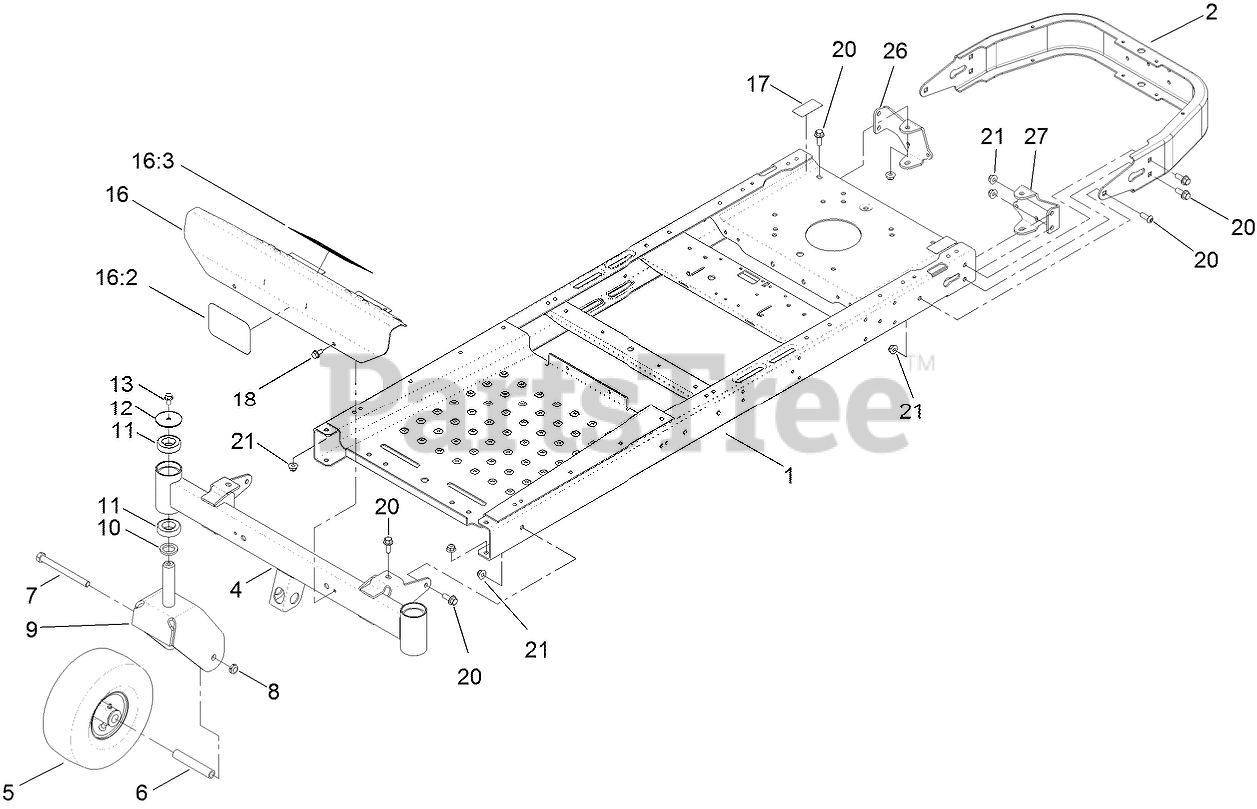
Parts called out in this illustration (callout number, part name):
2	BUMPER-REAR
4	AXLE-FRONT
5	CASTER WHEEL ASM (Cst)
6	BUSHING-SPANNER
7	SCREW-HH
8	NUT-LOCK, NI
9	FORK-CASTER
10	WASHER-THRUST
11	BEARING-BALL
12	WASHER
13	SCREW-HHF
16	FOOTREST ASM
16:3	DECAL-DANGER
17	DECAL-BYPASS
18	SCREW-HWHTF
20	SCREW-HHF
21	NUT-HF, NI
26	MOUNT-HYDRO, REAR (RH)
27	MOUNT-HYDRO, REAR (LH)
